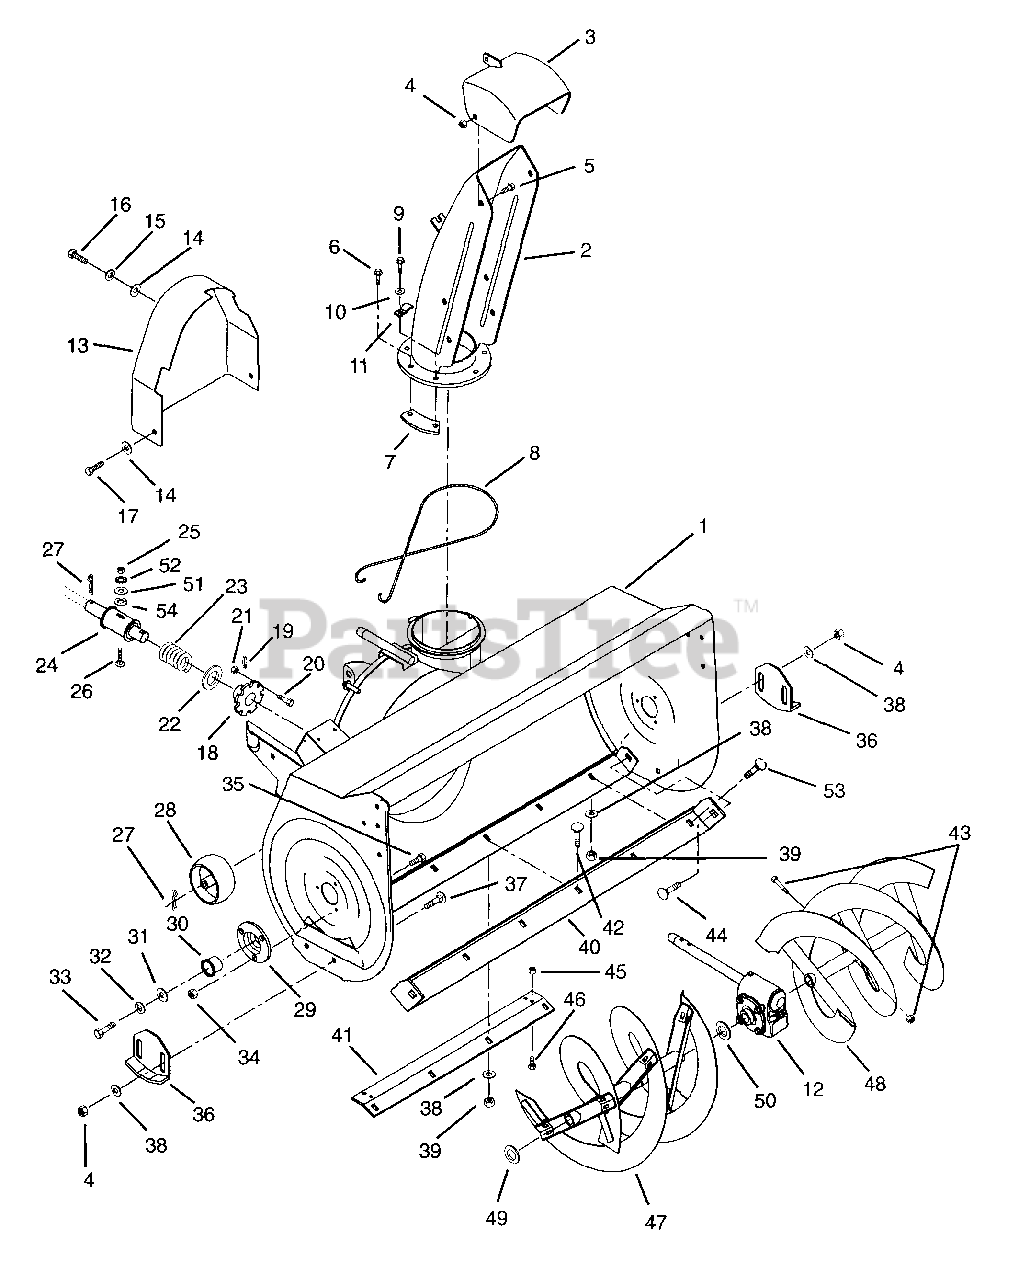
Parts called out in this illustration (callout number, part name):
1	40" SNO-THRO HOUSING W/DECALS
1	36" SNO-THRO HOUSING W/DECALS
2	DISCHARGE CHUTE
3	DEFLECTOR W/DECAL
4	@NUT-LK-CTR .38-16 YWZC
5	@BLT-HEX .38-16X.75 GR5 YWZC
6	@SCR-TAP 12-24X.50 HWH TR YWZC
7	CHUTE CLAMP
9	@SCR-TAP 12-24X.75 HWH YWZC
10	WSHR-FL-STL .188X.438X.049 PL
11	CABLE CLAMP
12	GEAR CASE - 40" - CAST IRON
13	BELT GUARD
14	@WSHR-FL-STL.38X.875X.083 YWZC
15	@WSHR-LK .31X.078 REG YWZC
16	@BLT-HEX .31-18X.75 GR5 YWZC
17	@SCR-TAP .31-18X.50 HWH TR YWZ
18	DISC ASSEMBLY
19	PIN-ROLL .188X1.00
20	SCR-SKH 10-24X.38
21	NUT-LK-DUAL FACE 10-24 YWZC
22	@WSHR-FL-STL.656X1.31X.095 YWZ
23	SG-COMP .054X.75X1.6
24	SPOOL
25	@NUT-HEX .25-20 YWZC
26	@BLT-RDHDSQNK .25-20X.75 G5YZ
27	PIN-HAIR INT .08X.38X1.42 YWZC
29	BEARING SUPPORT
30	BSHG-FLG 1.000X1.12X.62X1.50BR
31	WSHR-FL-STL.511X1.441X.125 YWZ
32	WSHR-LK .500X.151 HVY YWZC
33	@BLT-HEX .50-13X1.00 GR5 YWZC
34	@NUT-SPNLK-FLG .25-20 YWZC
35	BLT-SERNK SL .25-20X.50 YWZC
36	RUNNER-SKID SHOE
37	BLT-RHHDSQSHNK .38-16X.75 G2YZ
38	@WSHR-FL-STL.406X.812X.065 YWZ
39	@NUT-LK-CTR .31-18 YWZC
40	SCRAPPER BLADE - 40"
40	SCRAPPER BLADE - 36"
41	BLADE BRACE - 40"
41	BLADE BRACE - 36"
42	@BLT-RDHDSQNK .31-18X1.00 G5YZ
43	SHEAR BOLT SERVICE ASSEMBLY
44	@BLT-RDHDSQNK .38-16X1.00 G2YZ
45	@NUT-LK-CTR .38-16 YWZC
46	@BLT-HEX .38-16X.75 GR5 YWZC
47	R. H. RAKE W/ZERKS - 40"
47	RAKE, RIGHT-36"(1ID X 15.75OD)
48	L. H. RAKE W/ZERKS
48	RAKE, LEFT-36"(1"ID X 15.75OD)
49	WSHR-FL-STL 1.010X1.505X.062YZ
50	SEAL 1.625X2.125X.250
51	@WSHR-FL-STL.281X.62X.065 YWZC
52	@WSHR-LK-EXT.262X.502X.026YWZC
53	@BLT-RDHDSQNK .31-18X.75 G5YZ
54	WSHR-LK PYM .31X.062YWZC
